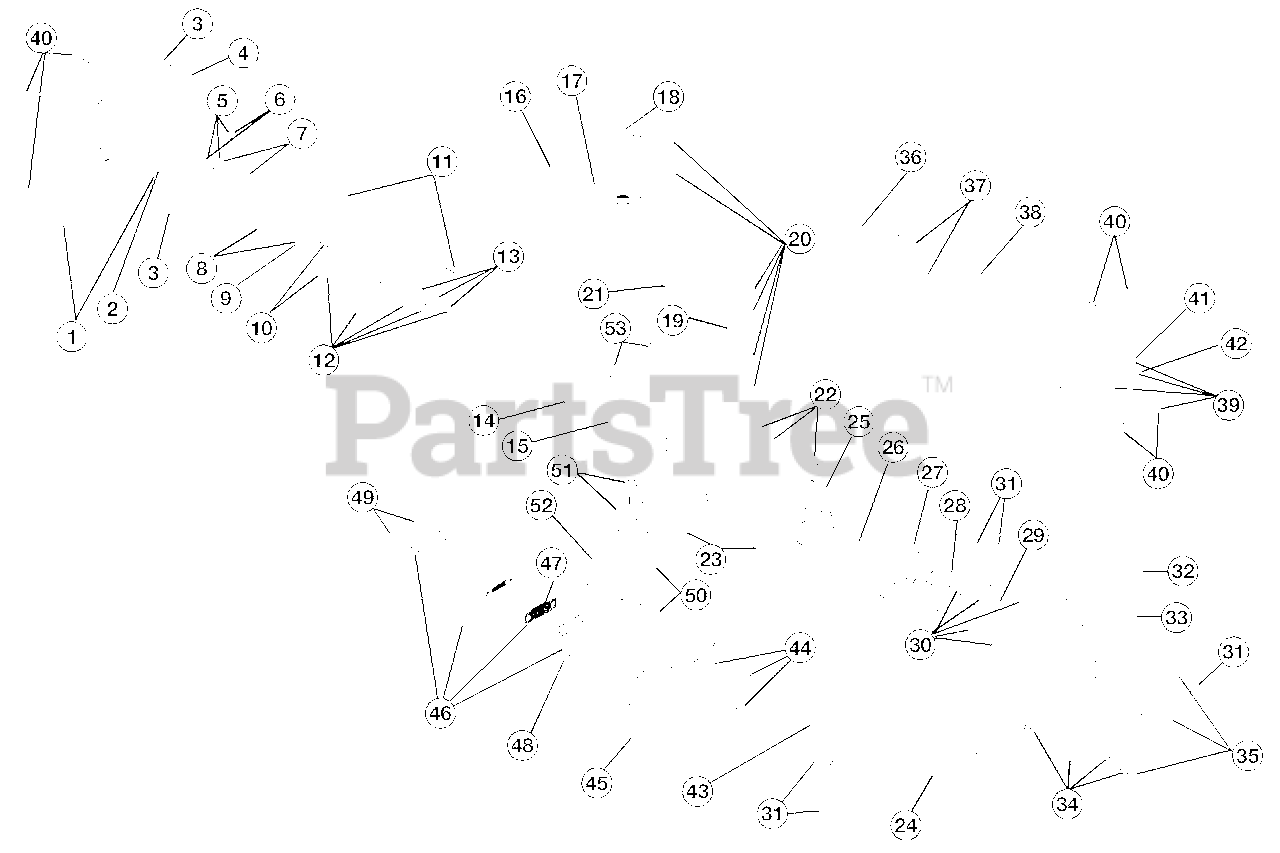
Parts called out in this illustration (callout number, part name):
1	Air Cleaner/Muffler Cover Assembly
2	Air Cleaner Filter
3	Carburetor Mounting Screw Assembly
4	Wavey Washer
5	Choke Lever Assembly
6	Choke Knob and Screw
7	Choke Lever and Plate
8	Carburetor Assembly
9	Carburetor Gasket
10	Carb Mount Screw
11	Primer and Hose Assembly
12	Carb Mount Assembly
13	Reed Assembly
14	Carburetor Mount Gasket
15	Crank Case Service Assembly
16	Rear Mounting Pad
17	Fuel Tank Assembly
18	Fuel Cap Assembly
19	Fuel Return Line
20	Fuel Line Assembly
21	Front Mounting Pad
22	Shroud Assembly
23	Shroud Screw
24	Shroud Extension and Stand
25	Flywheel Assembly
27	Recoil Pulley Assembly
28	Recoil Spring
29	Rope Guide
30	Pulley Retainer Assembly
31	Switch Assembly
32	Pull Handle
34	Starter Housing Assembly
35	Housing Screw
36	Clutch Washer
37	Clutch Rotor Assembly
38	Clutch Drum Assembly
39	Clutch Cover Assembly
40	Cover Screw
41	Anti-Rotation Screw
42	Clamping Screw
43	Wire Lead
44	Module Assembly
45	Spark Plug
46	Muffler Assembly
47	Spark Arrestor Screen
48	Exhaust Gasket
49	Muffler Mounting Bolt Assembly
50	Cylinder Assembly
51	Piston and Rod Assembly
52	Cylinder Gasket
53	Cylinder Bolt
